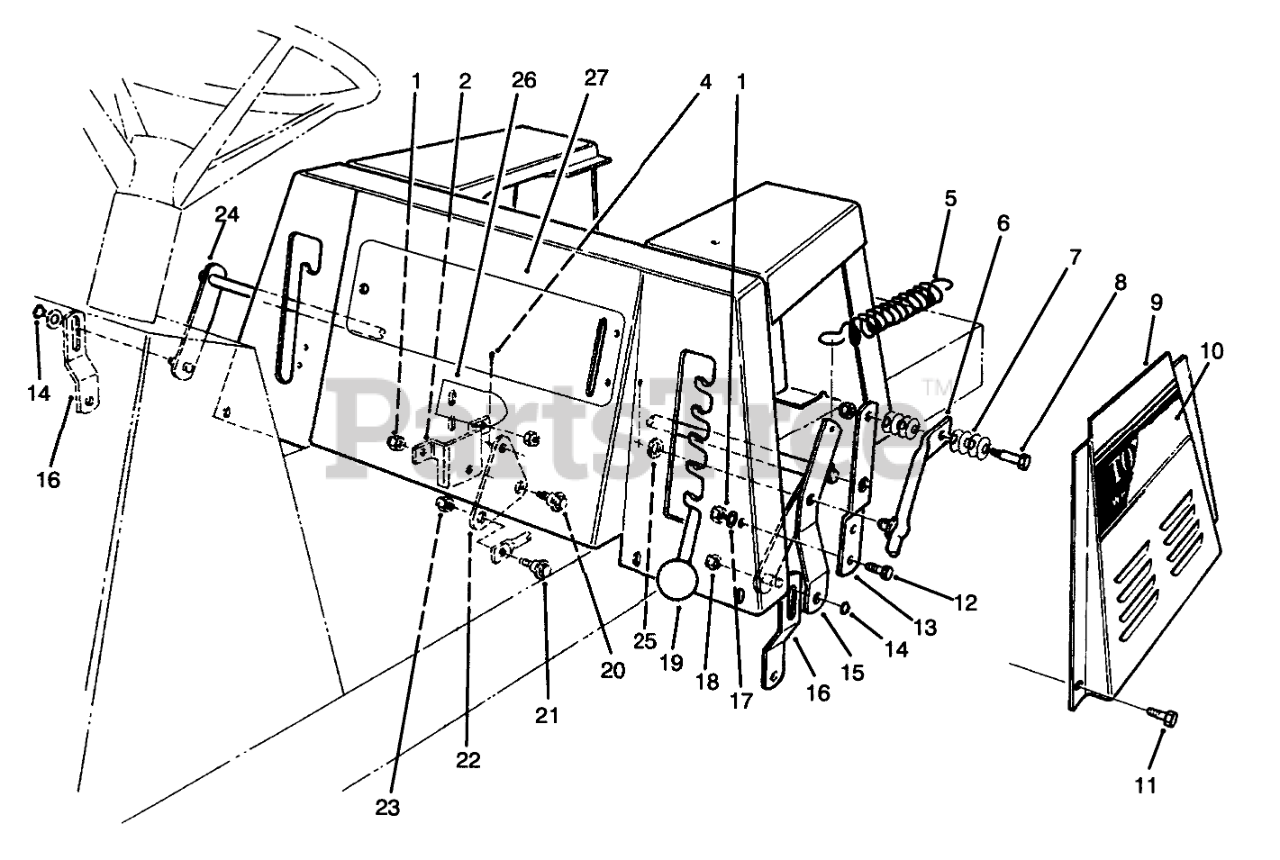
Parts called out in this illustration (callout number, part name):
1	NUT-LOCK, NI
2	BRKT-B.CRANK MTG
4	PIN-COTTER
5	SPRING-EXTENSION
6	HOC LEVER WA B
7	WASHER-BELLEVILLE
8	BOLT-SHOULDER
9	Panel L.H.-Base, Seat
10	DECAL - TORO 1232 LH
10	DECAL - TORO 1032 LH
11	SCREW-HH
12	SCREW-HH
13	Bracket
14	RING-RETAINING
15	Bracket-H.O.C., Engage
16	Link-Deck Suspension
17	WASHER-PLAIN
18	NUT-LOCK, NI
20	SCREW-SHOULDER
21	SCREW-SHOULDER
22	BELLCRANK
23	NUT-HEX
24	Arm
25	WASHER-FLAT
26	DECAL - USA
27	DECAL - CONTROL PANEL
